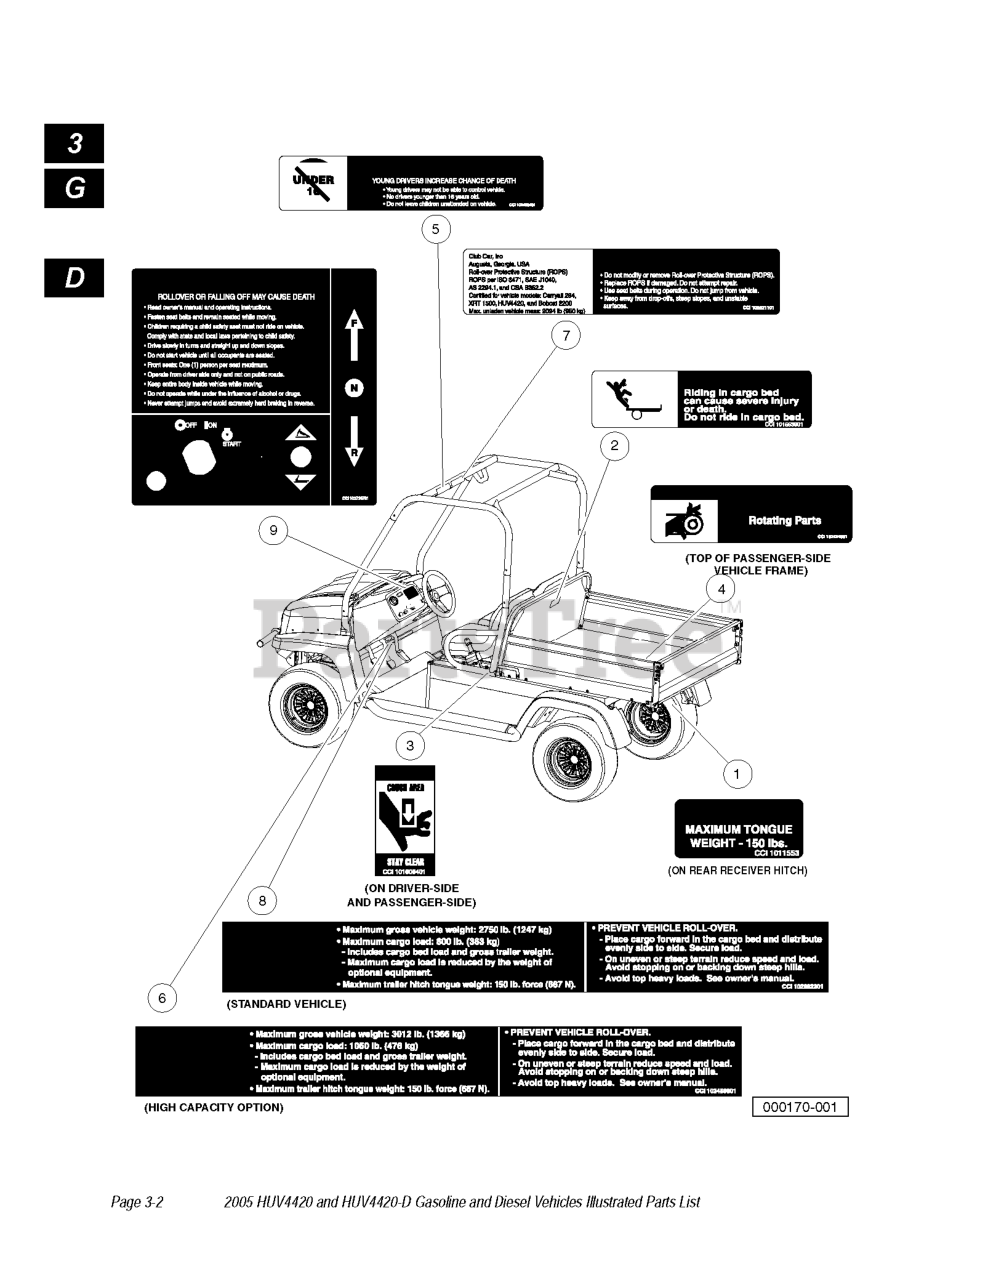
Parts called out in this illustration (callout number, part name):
1	DECAL, TRAILER HITCH
2	DECAL, BED LOAD WARNING
3	DECAL, CRUSH AREA WARNING
4	DECAL-ROTATING PARTS
5	DECAL, WARNING UNDER 16
6	DECAL, VEH LOAD HIGH CAPACITY
7	DECAL, WARNING-CERTIFIED ROPS
8	DECAL, VEHICLE LOAD, 2750 LBS
9	DECAL-WARNING-GAS
